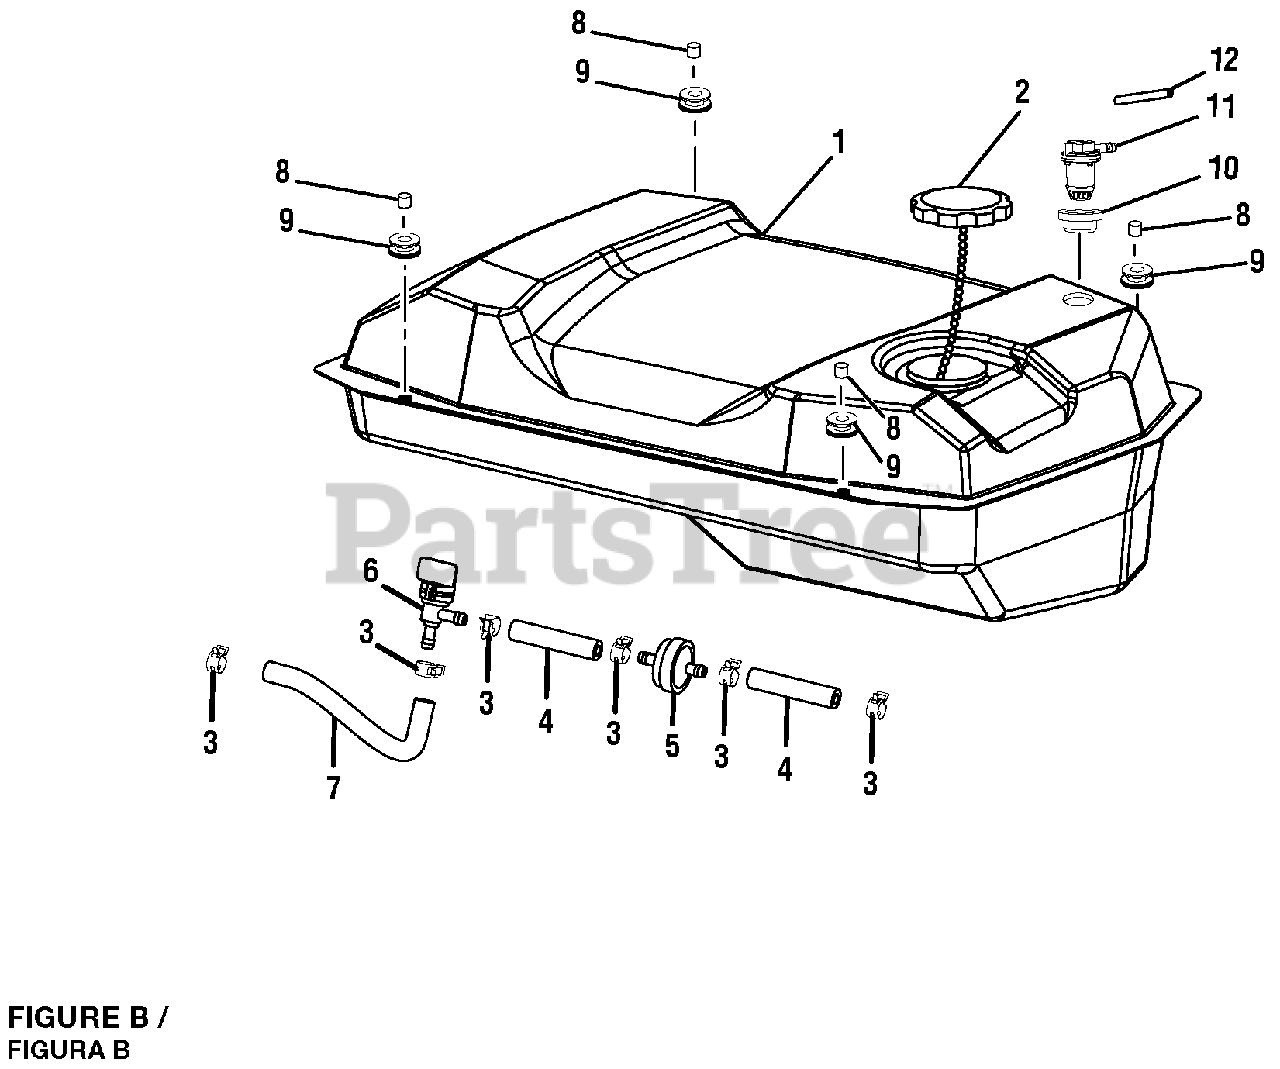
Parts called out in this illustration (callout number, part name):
1	Fuel Tank
2	Fuel Tank Cap
3	Fuel Line Clamp (1/2 in.)
4	Fuel Line (105 mm)
5	Fuel Filter
6	Fuel Shut Off Valve
7	Fuel Line (208 mm)
8	Spacer (Fuel Tank Isolator)
9	Bushing (Fuel Tank Isolator)
11	Rollover Valve
12	Rollover Hose
